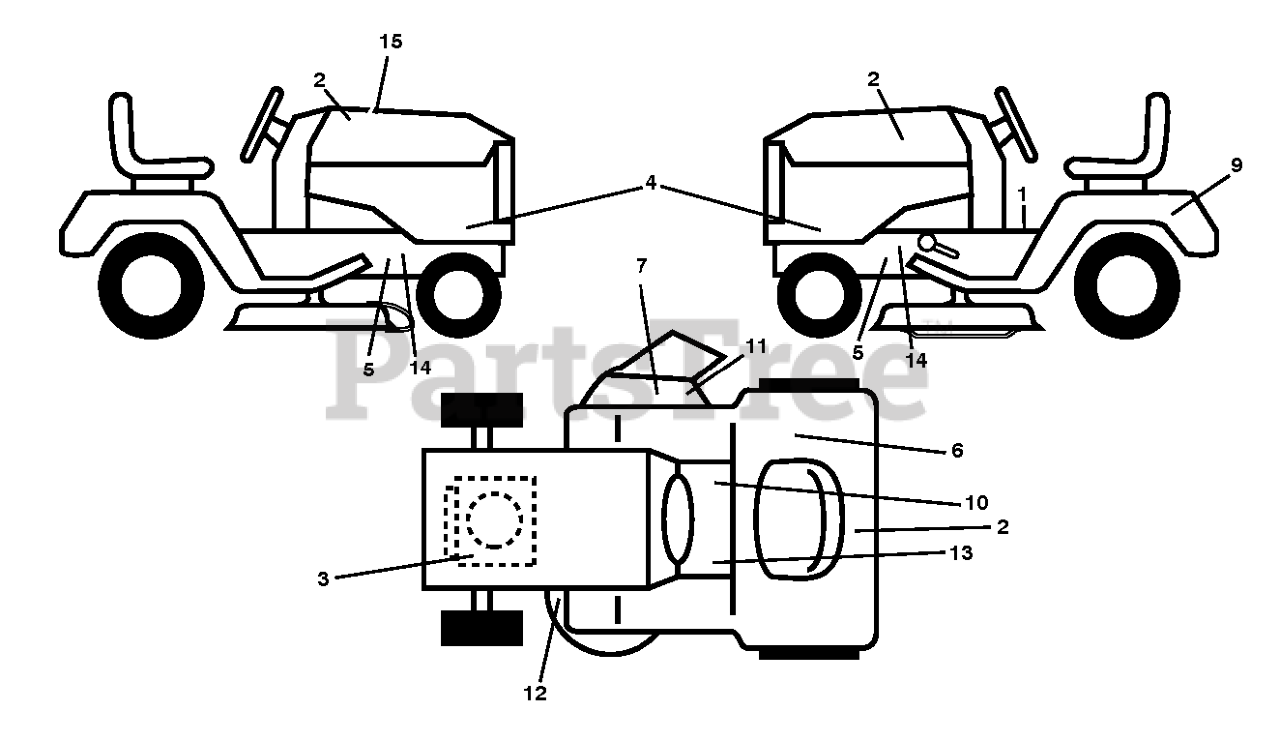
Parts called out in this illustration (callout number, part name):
1	LABEL
2	DECAL.HOOD.LOGO.ORANGE.HUSQVAR
3	DECAL
6	Decal, Fender 100 DB/CE
7	DECAL.INTERNATIONL.CUTFINGER
9	DECAL BTRY SYMBOLS
10	DECAL PARK BRAKE
11	DECAL, DEFLECT WARNING
12	DECAL.V-BELT.SCHEMATIC.36/38/9
13	DECAL
